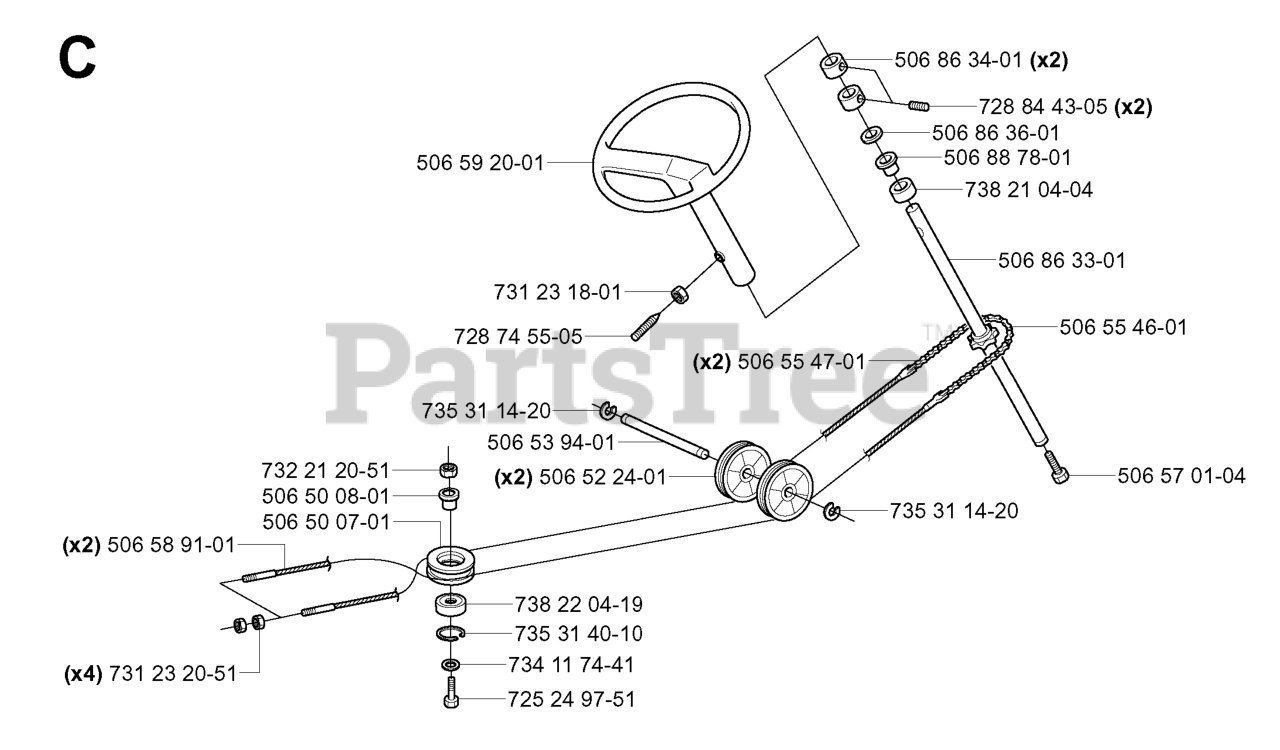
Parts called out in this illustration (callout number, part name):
2	VALVE STEM LT
3	RIM.ASM.8X5.FRONT.SILVER
4	TUBE.16X6.5/7.5-8
5	TIRE.16X6.5-8.TURF.MASTER
6	FITTING LT.
7	BEARING.FLANGE
8	CAP, AXLE BLK
9	TIRE REAR.TM22X9.5-12.C.SERVIC
10	TUBE.23X9.5-12
11	RIM.ASM.12".REAR.SILVER
12	CAP.HUB.GT.PM.BLACK
